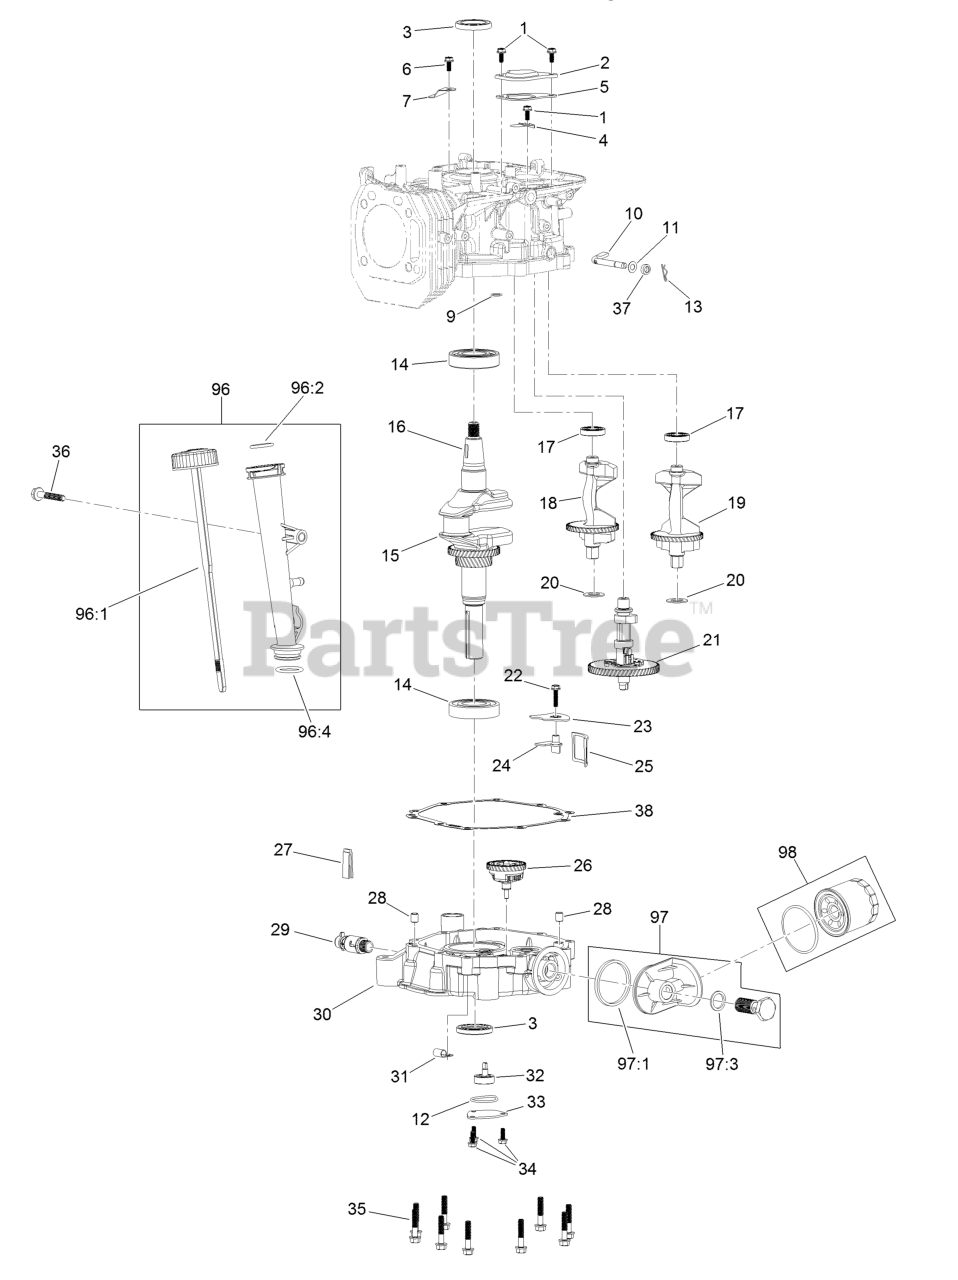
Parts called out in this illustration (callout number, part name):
1	SCREW-HHF
2	PLATE-BREATHER
3	SEAL-OIL
4	VALVE-REED
5	GASKET-BREATHER
6	SCREW-HHF
7	RETAINER
10	SHAFT-GOVERNOR
11	WASHER-PLAIN
12	SEAL-PUMP, OIL
13	PIN-HAIR
14	BEARING-BALL
15	CRANKSHAFT
16	KEY-WOODRUFF
17	BEARING-BALL
18	SHAFT-BALANCE, R
19	SHAFT-BALANCE, L
21	CAMSHAFT
22	SCREW-HHF
23	COVER-STRAINER, OIL
24	PLATE-BAFFLE, OIL
25	STRAINER-OIL
26	GEAR-GOVERNOR
27	DEFLECTOR-OIL, RUBBER
28	PIN-DOWEL
29	VALVE-DRAIN, OIL
30	COVER-CRANKCASE
31	CLAMP-HOSE
32	OIL PUMP ASM
33	COVER-PUMP, OIL
34	SCREW-HHF
35	SCREW-HHF
36	SCREW-HHF
37	SEAL-OIL
38	GASKET-CRANKCASE
96	DIPSTICK AND TUBE KIT
96:1	DIPSTICK ASM
97	OIL ADAPTOR KIT
97:1	SEAL-ADAPTOR, OIL
97:3	WASHER-FILTER, OIL
